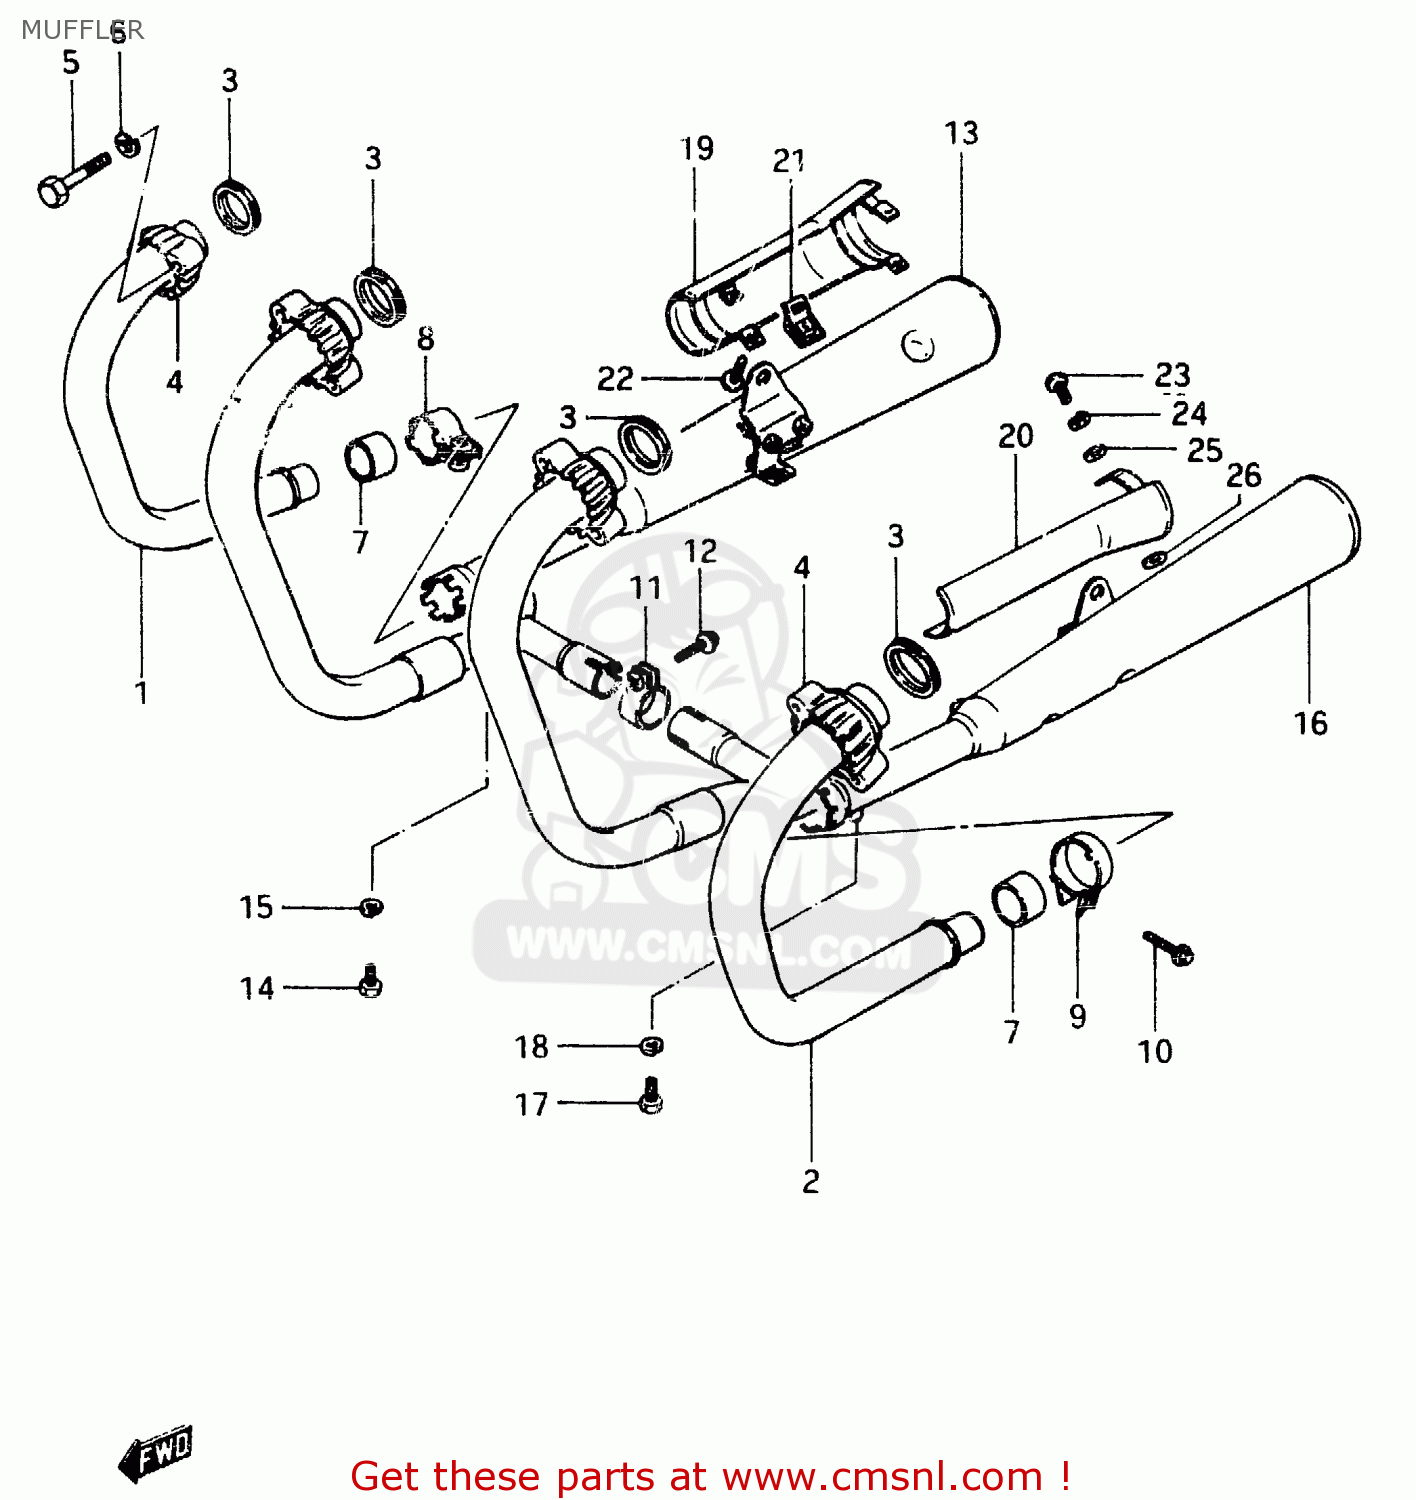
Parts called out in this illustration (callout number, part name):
1	PIPE, EXHAUST RH
2	PIPE, EXHAUST LH
3	GASKET,EXHAUST PIPE (NAS)
4	CLAMP,EXHAUST PIPE
5	BOLT 8X40
6	LOCK WASHER
7	CONNECTOR,MUFFLER
8	CLAMP,MUFFLER CONNECTOR
9	CLAMP,MUFFLER CONNECTOR
10	BOLT
11	CLAMP,EXHAUST COUPLER
12	BOLT
13	MUFFLER, RH
14	BOLT
15	WASHER
16	MUFFLER, LH
17	BOLT
18	WASHER
19	COVER, MUFFLER RH
20	COVER, MUFFLER LH
21	CLAMP
22	SCREW
23	SCREW
24	WASHER,LOCK
25	WASHER,5MM
26	GASKET 6.2X12X1.5 (MCA)
